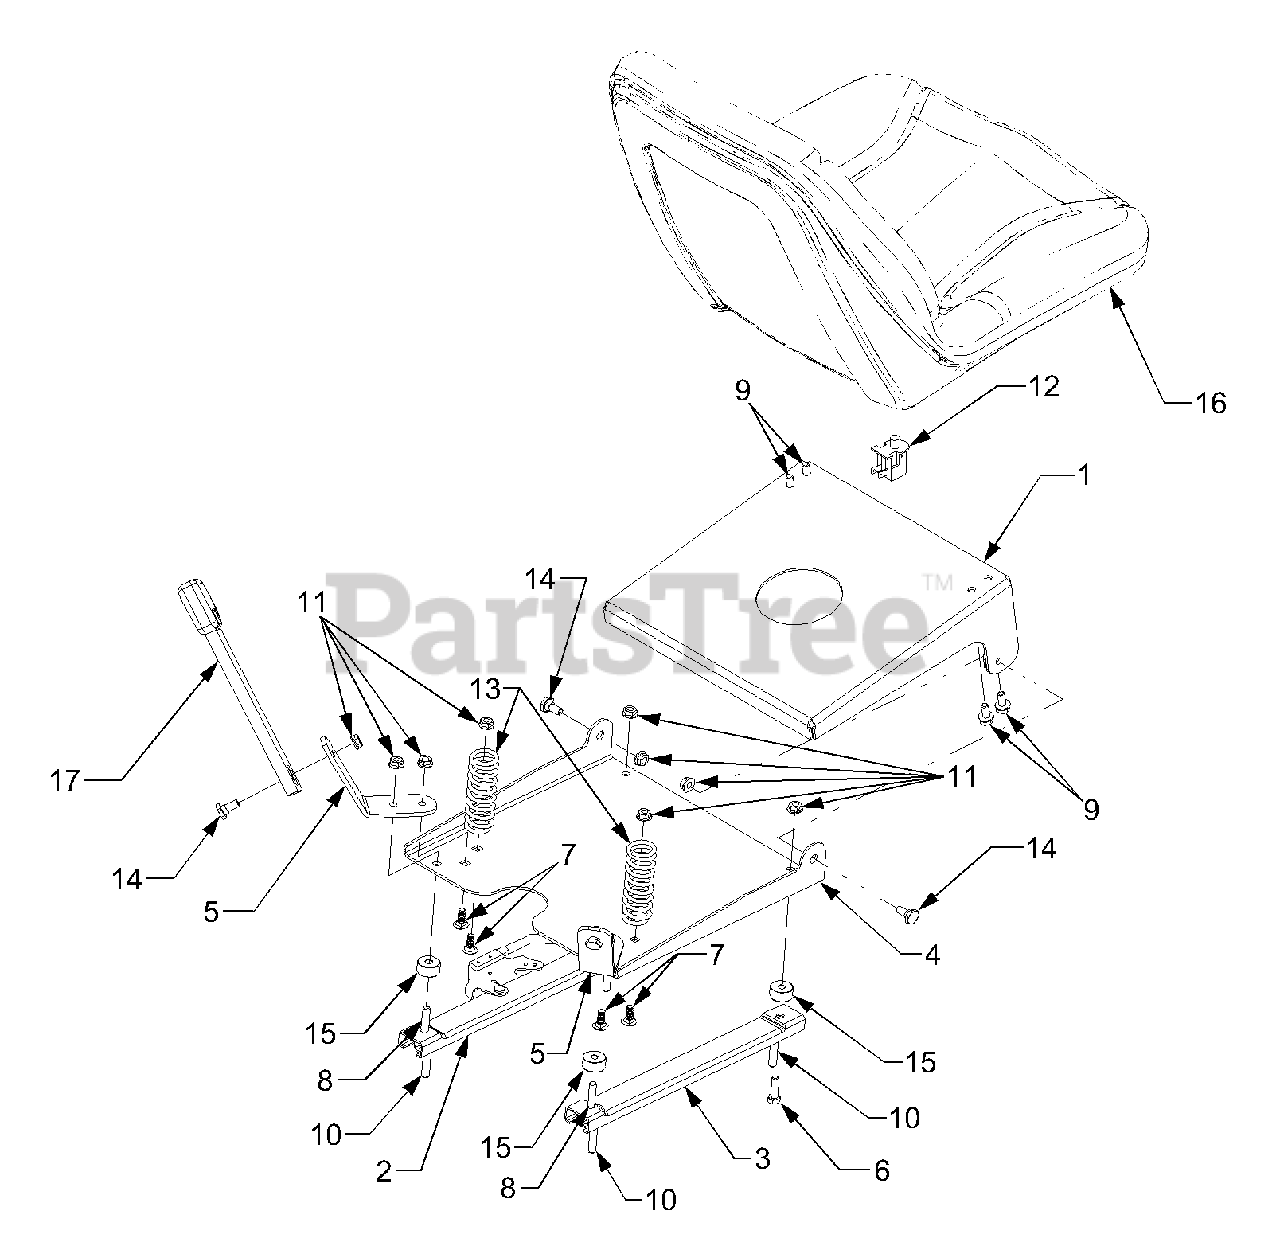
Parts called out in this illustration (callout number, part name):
1	Support, Seat - Upper
2	Track Ass'y., Seat w/Latch
3	Track Ass'y., Seat w/o Latch
4	Tray, Lower Seat
5	Bracket, Seat Belt
6	Screw, Hex Cap, 5/16-18 x 1.0 GR5
7	Screw, Carriage, 5/16-18 x .75
8	Screw, Hex Cap, 5/16-18 x 1.25 GR5
9	Screw, Hex Flange, 5/16-18 x .625 GR5
10	Screw, Socket Hd Cap, 5/16-18 x 1.5
11	Nut, Hex Flange Lock, 5/16-18
12	Switch, Snap Mount (N.O.)
13	Spring, Compression, 1.28 x 3.5
14	Screw, Shoulder, .435 x .178-5/16-18
15	Spacer, .315 x .750 x .375
16	Seat, High Back
17	Belt Assembly, Seat
